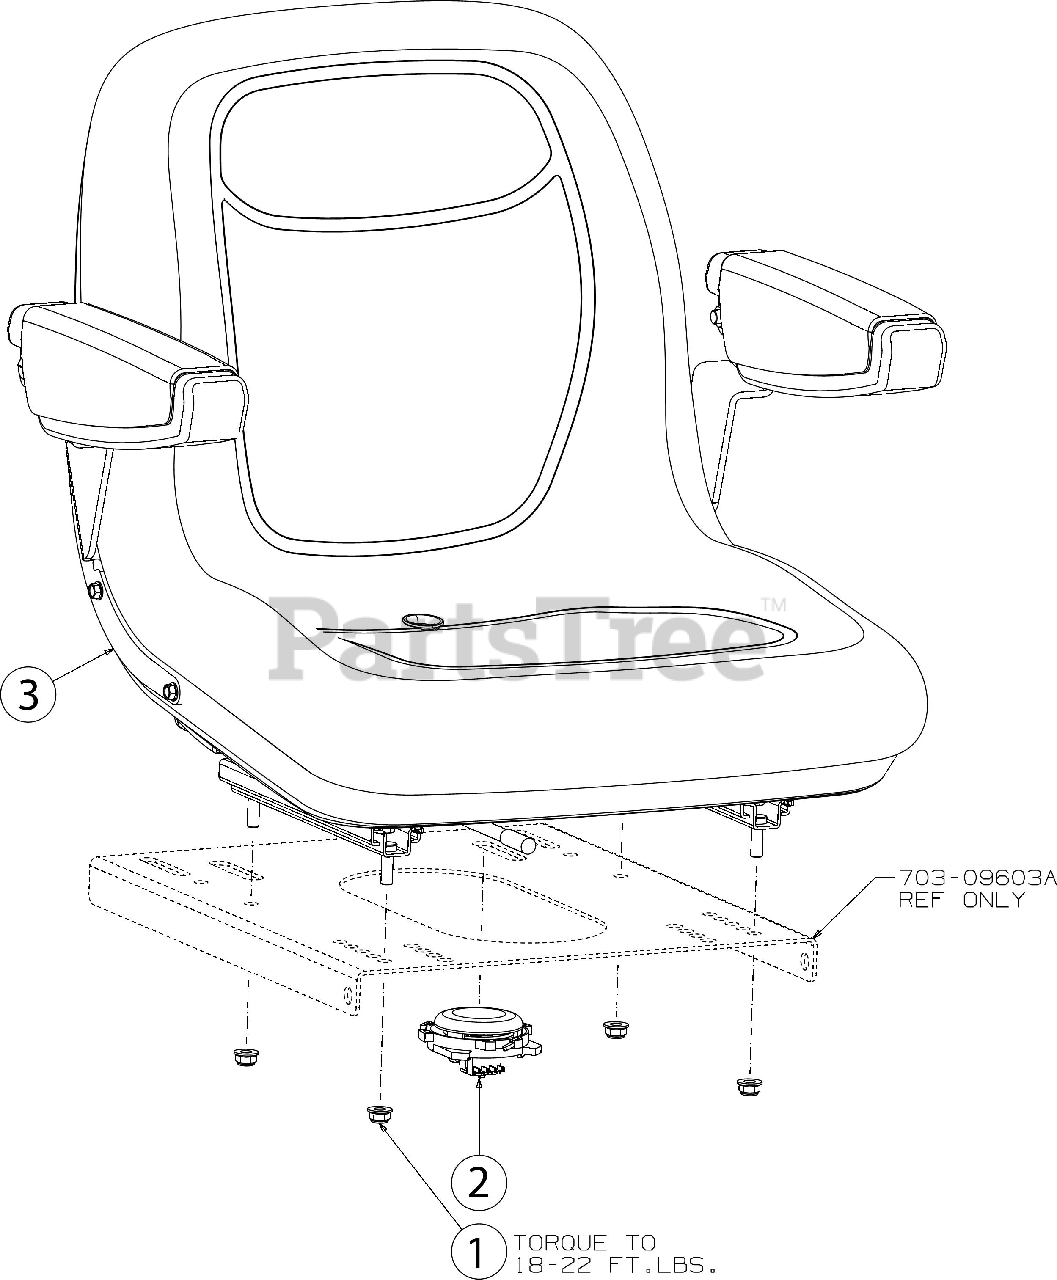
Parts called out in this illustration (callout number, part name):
1	FLANGE LOCK NUT 5/16-18
2	SEAT SWITCH NC/NC
3	SEAT ASSEMBLY W/ARMREST
